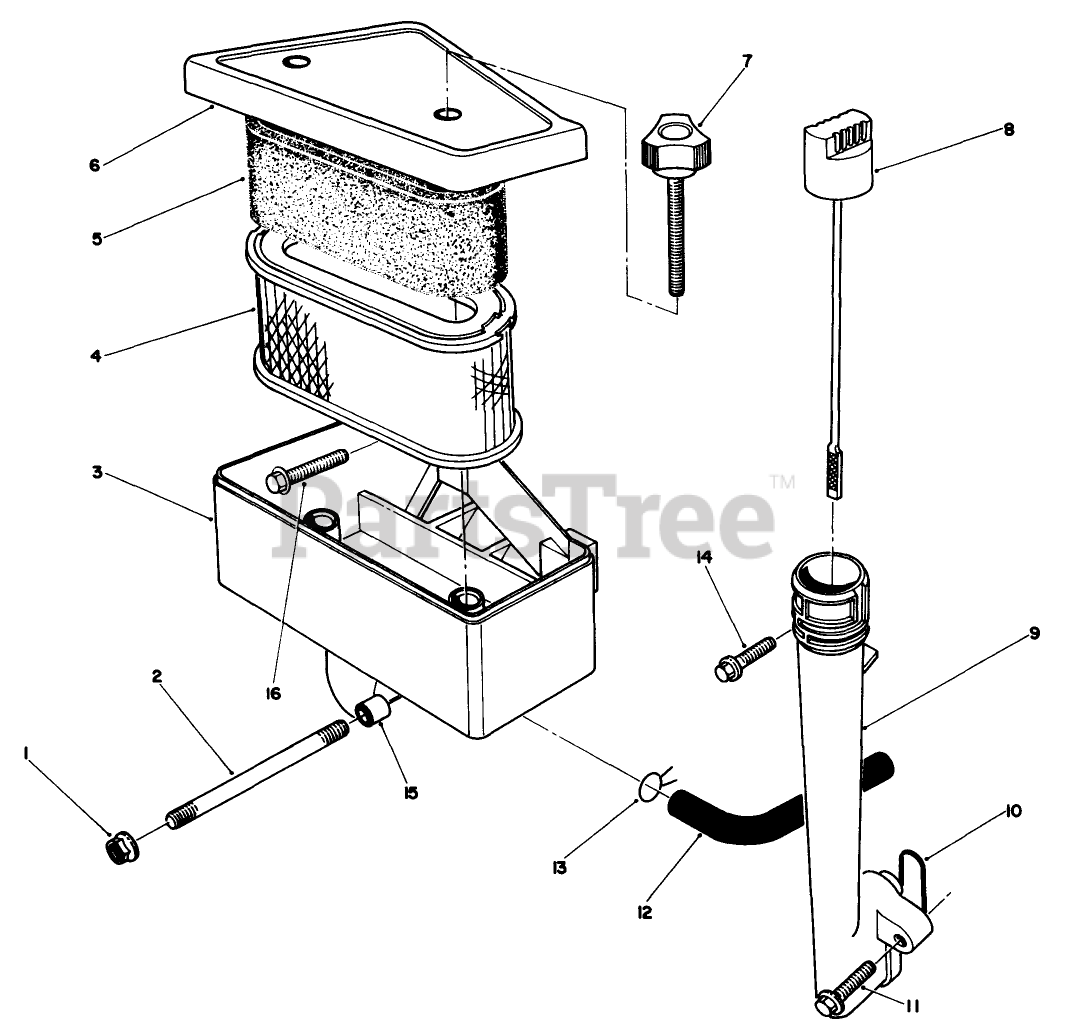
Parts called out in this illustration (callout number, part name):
3	AIR CLEANER BODY
4	AIR FILTER ELEMENT
5	Filter-Foam
6	AIR CLEANER COVER *B
7	RETAINER - COVER
10	O-RING
13	CLAMP F/W ENGINE
15	SPACER
